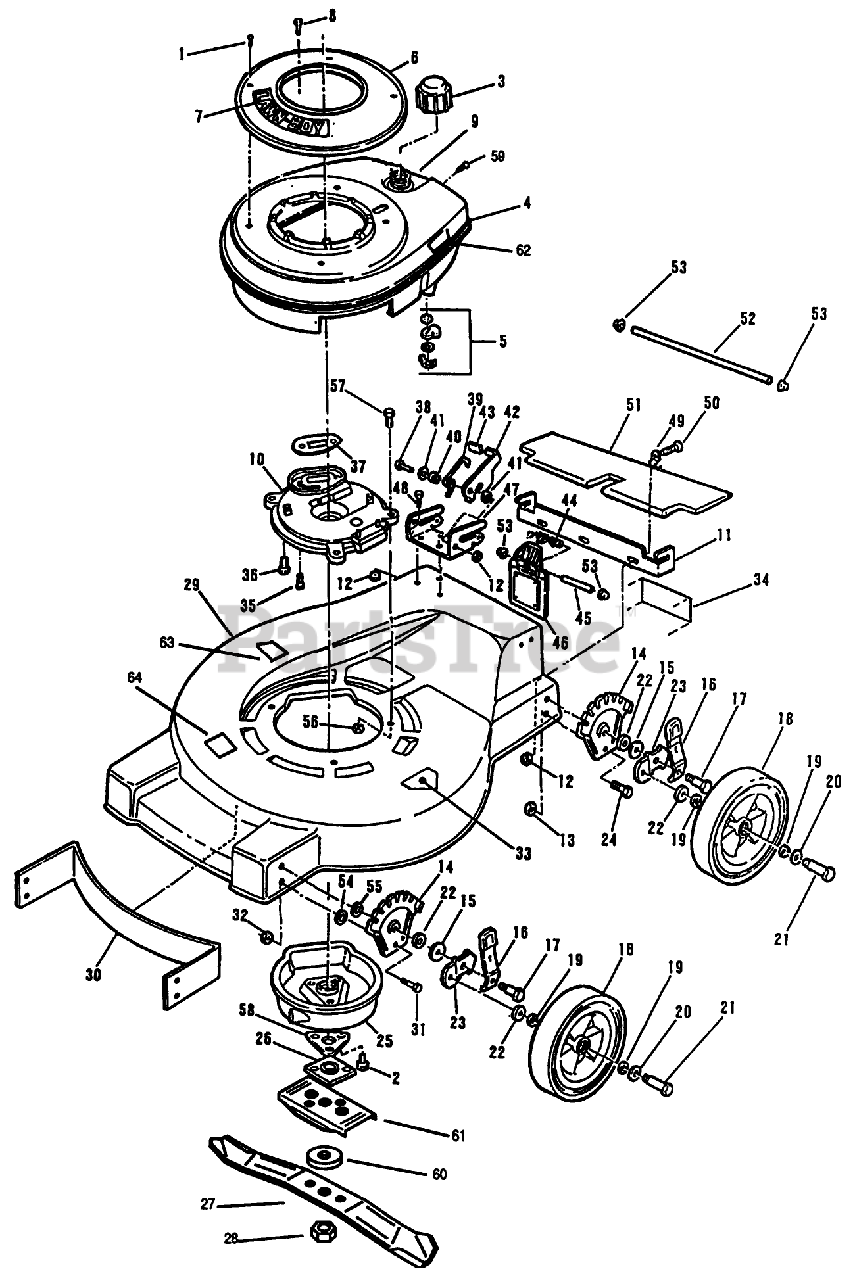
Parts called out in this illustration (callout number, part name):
1	SCREW - SELF TAPPING
2	SCREW
3	FUEL CAP & INSERT
4	SHROUD,TANK&VAL
5	SHUT OFF VALVE KIT
8	SCREW SEMS SM
10	PLATE,MUFFLER F
12	LOCKNUT E
13	LOCKNUT
15	WASHER
16	KNOB&SPRING FORMCO
17	BOLT
19	WASHER
20	SPACER
21	BOLT WHEEL
22	WASHER WROUGHT
26	PLATE AND COLLAR ASM
28	NUT-BLADE
32	LOCKNUT
35	SCREW V
37	GASKET-EXHAUST F
39	SPRING
43	KNOB (S&R)
44	SPRING ASOC
45	ROD ROCK/HDWE
51	T/SHIELD SM&P
54	WASHER
55	WASHER
56	NUT-LOCK F
57	SCREW-HH
58	SUPPORT F
59	SCREW S
60	WASHER
